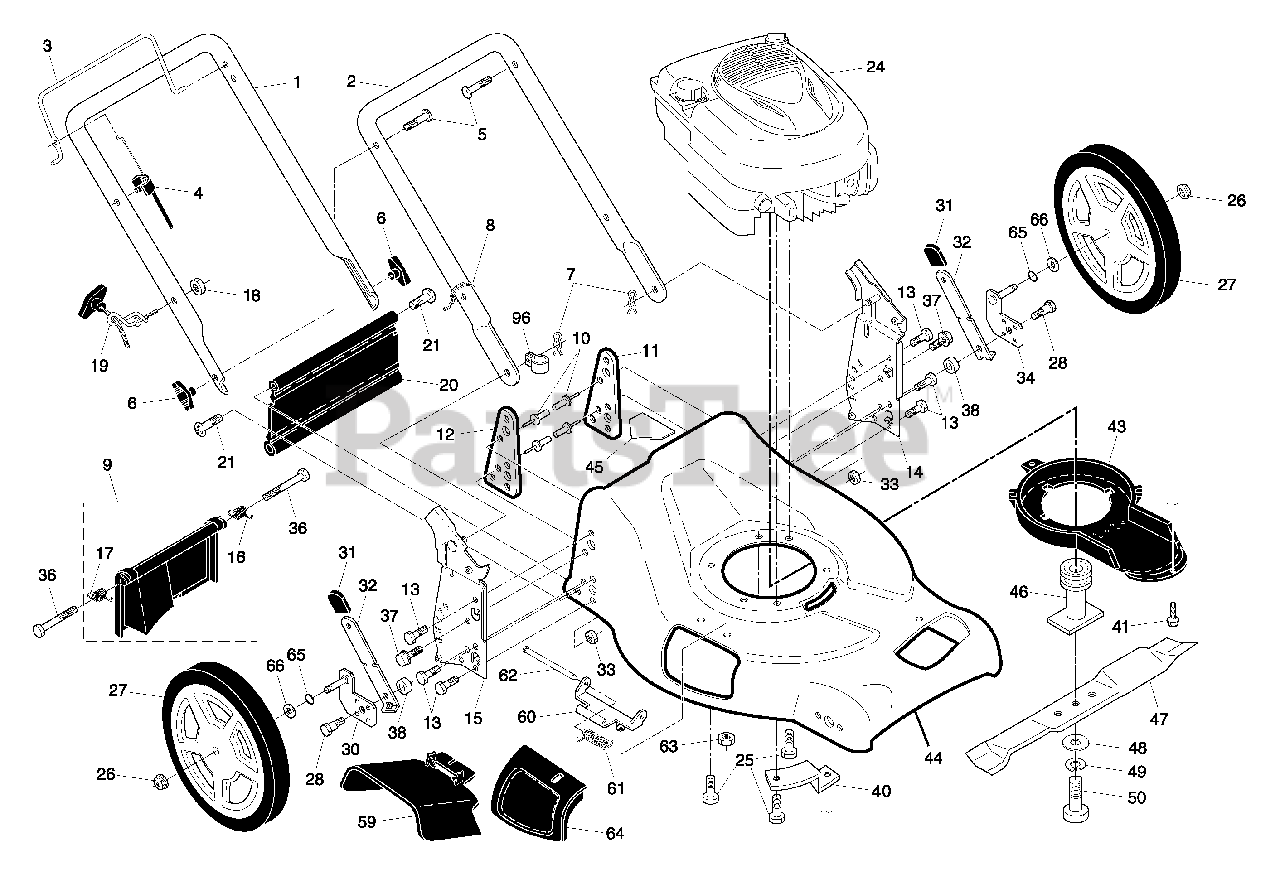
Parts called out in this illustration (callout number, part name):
1	Upper Handle
2	Lower Handle
3	Control Bar
4	Engine Zone Control Cable
5	Handle Bolt
6	Handle Knob
7	Hairpin Cotter
8	Wire Tie
9	Kit, Rear Door
10	Pop Rivet
11	Support Bracket, LH
12	Support Bracket, RH
13	Screw, Tapping 1/4-20 x 5/8
14	Handle Bracket Assembly, LH
15	Handle Bracket Assembly, RH
16	Spring, Rear Door, LH
17	Spring, Rear Door, RH
18	Nut, Hex 1/4-20
19	Rope Guide
20	Rear Skirt
21	Hinge Screw 1/4-20 x 1-1/4
25	Hex Head Thread Rolling Screw 3/8-16 x 1-1/8
26	Hex Flange Nut
27	Wheel & Tire Assembly, Rear, 12"
28	Shoulder Bolt 5/16-18 x 1-21/64
30	Axle Arm Assembly, Rear, RH
31	Selector Knob
32	Selector Spring
33	Locknut, Hex
34	Axle Arm Assembly, Rear, LH
36	Bolt, Rear Door
37	Screw, Hex Washer Head 5/16-18
38	Washer, Step
40	Mounting Bracket, Debris Shield
41	Screw, Debris Shield
43	Debris Shield
44	Kit, Lawn Mower Housing
45	Danger Decal
46	Blade Adapter / Pulley
47	Blade, 21"
48	Hardened Washer
49	Helical Washer
50	Hex Head Machine Screw, Grade 8, 3/8-24 x 1-3/8
59	Discharge Defl ector
60	Hinge Bracket
61	Spring
62	Rod, Hinge
63	Keps Locknut 1/4-20
64	Mulcher Door
65	O-Ring
66	Washer, Flat
96	Clip, Cable
